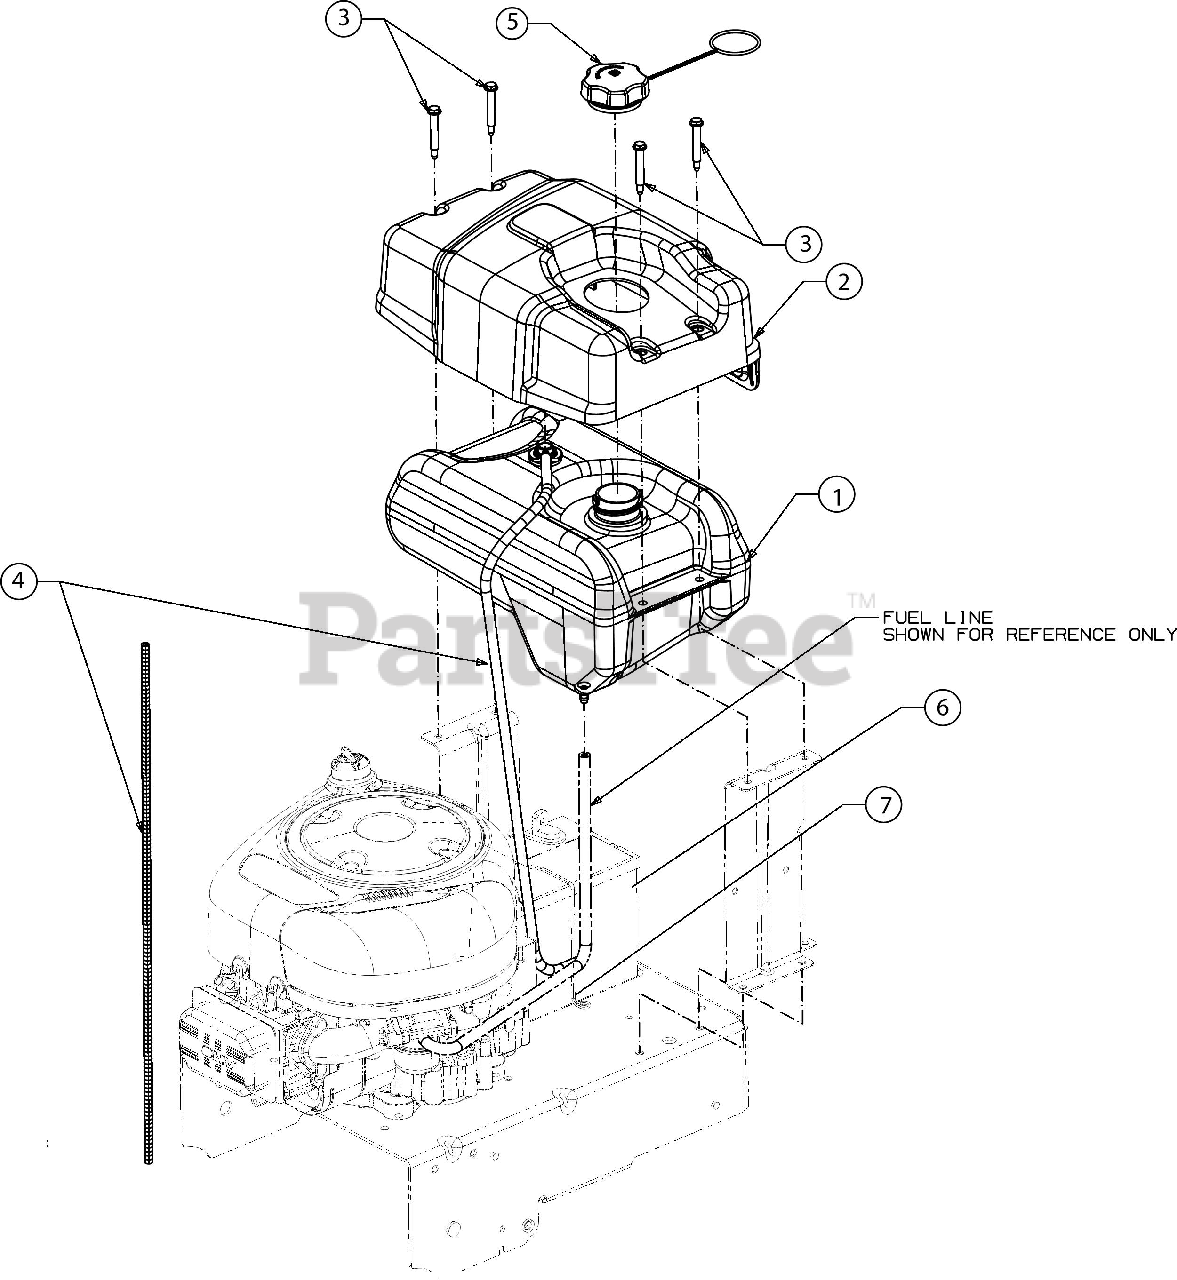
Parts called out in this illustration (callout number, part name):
1	FUEL TANK ASSEMBLY
1	RUBBER GROMMET 23.0 ID X 35.5 OD
1	ROLLOVER FUEL VALVE
2	FUEL TANK COVER
3	SHOULDER BOLT .32X1.8X1/4
4	VENT HOSE 3/16 ID
5	FUEL CAP W/HOOP
7	BATTERY HOLD DOWN STRAP
